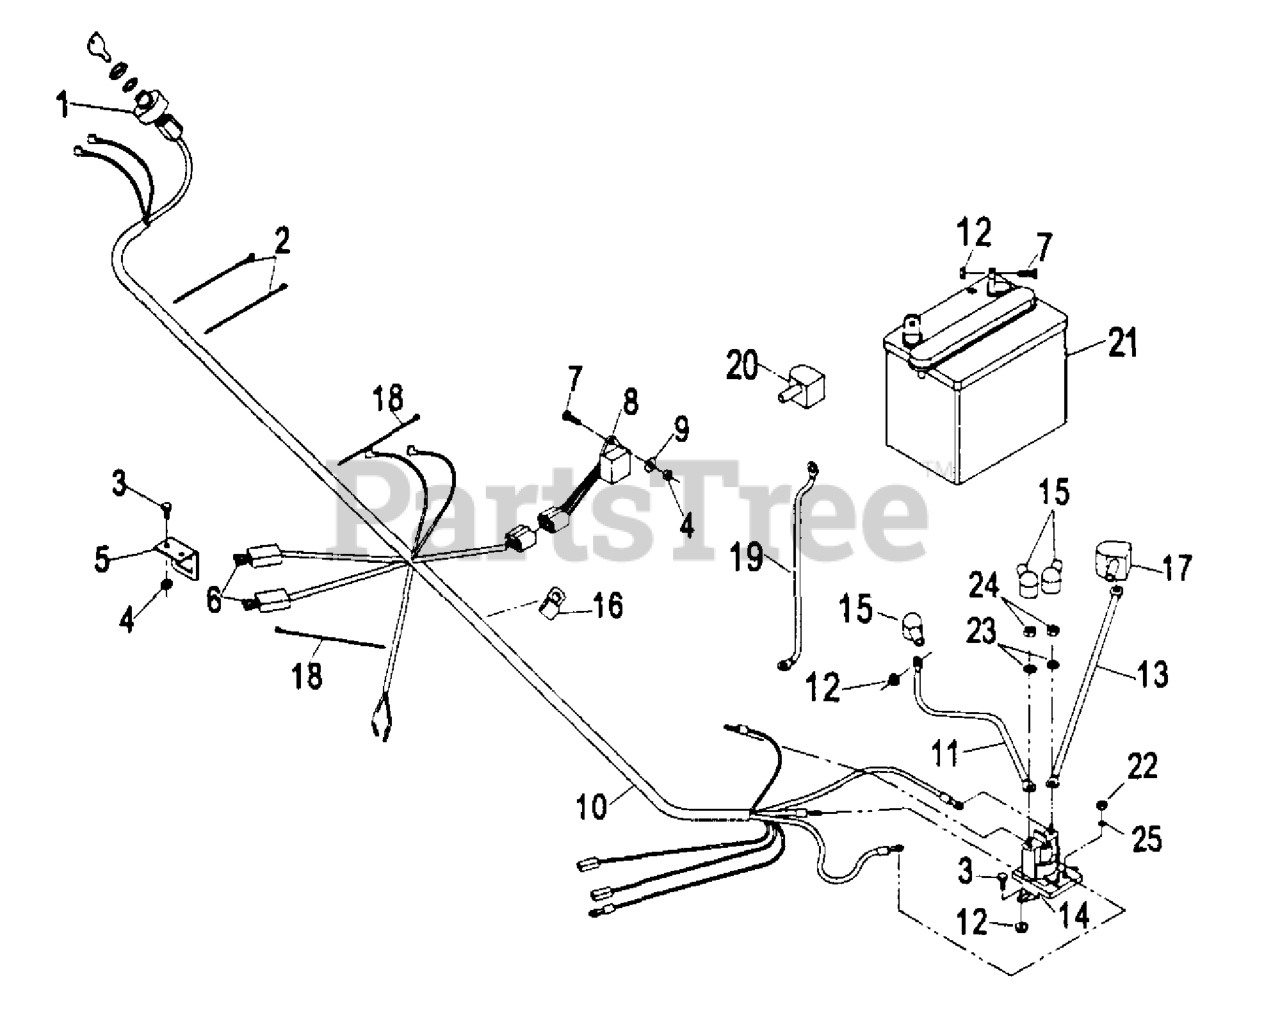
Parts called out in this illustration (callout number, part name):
1	SWITCH,IGNITION
2	TIE-PLASTIC
5	BRACKET,FUSE
6	FUSE-BLADE TYPE, 20 AMP
8	MODULE-OPC NO TIME DELAY
15	INSULATOR-SOLENOID
16	CLIP-LOOM
18	TIE-CABLE
19	CABLE-BATTERY, NEGATIVE
20	INSULATOR, BATTERY -
21	Battery, 12v Mnfld
22	NUT-HEX
23	WASHER-LOCK
25	WASHER-LOCK
